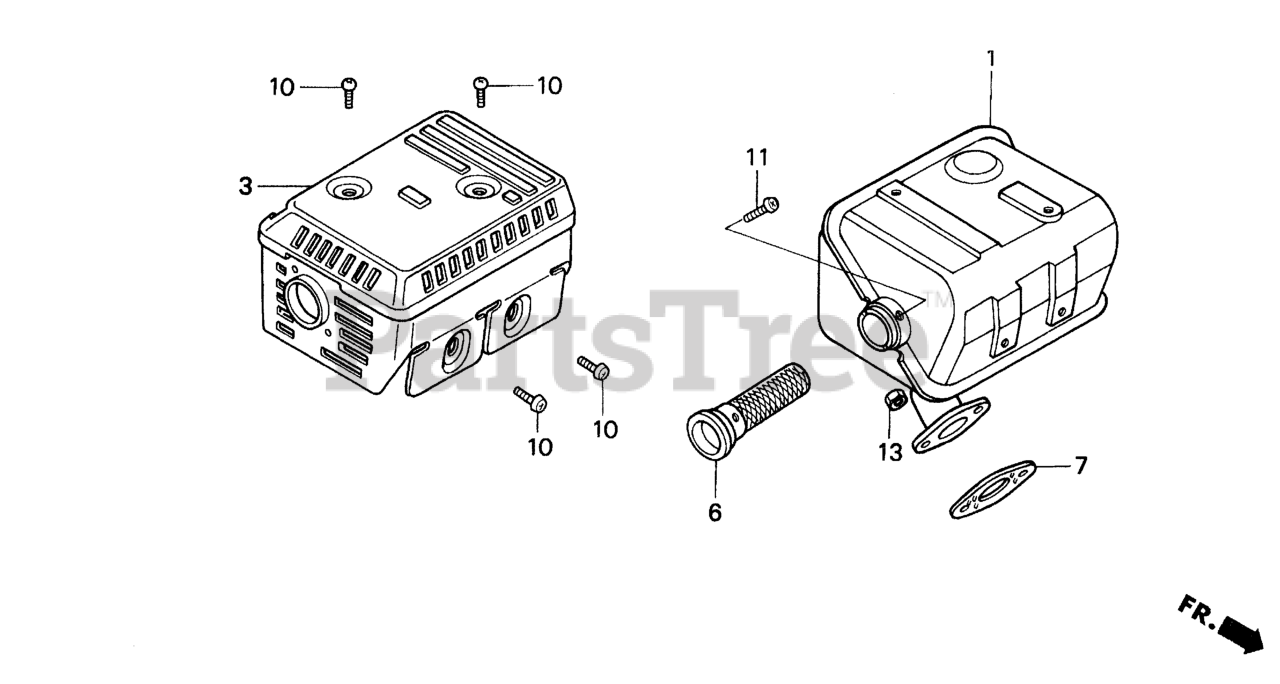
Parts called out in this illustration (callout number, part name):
1	MUFFLER (STD) Use up to Engine SN 1869307.
3	PROTECTOR, MUFFLER (STD) (BLACK)
6	ARRESTER, SPARK
7	GASKET, MUFFLER
10	SCREW, TAPPING (5X8)
13	NUT, HEX. (8MM)
